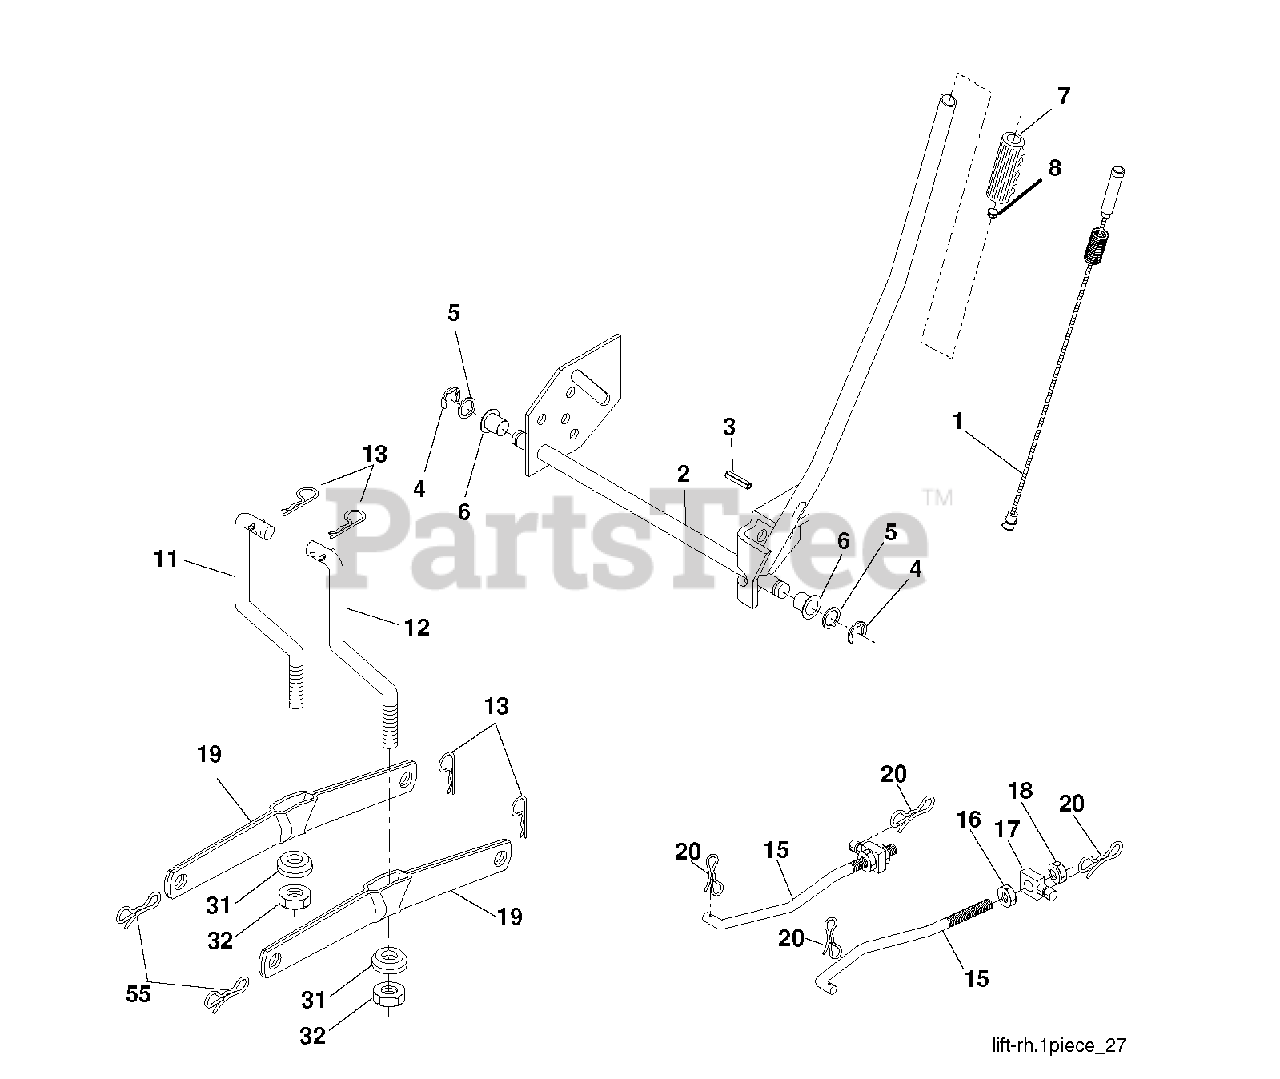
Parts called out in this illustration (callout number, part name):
4	RETAINING RING LT
6	BEARING.NYLON
7	GRIP
11	LINK LIFT LH
12	LINK LIFT RH
13	RETAINER-SPRNG RB
15	LINK.SUSPENSION.FRONT
16	NUT
18	NUT
19	ARM.REAR.SUSPENSION
20	PIN.COTTER.7/16.BOW TI
31	BEARING.PIVOT.LIFT
32	NUT CROWNLOCK 3/8-24
55	PIN.COTTER.5/16.BOW TI
